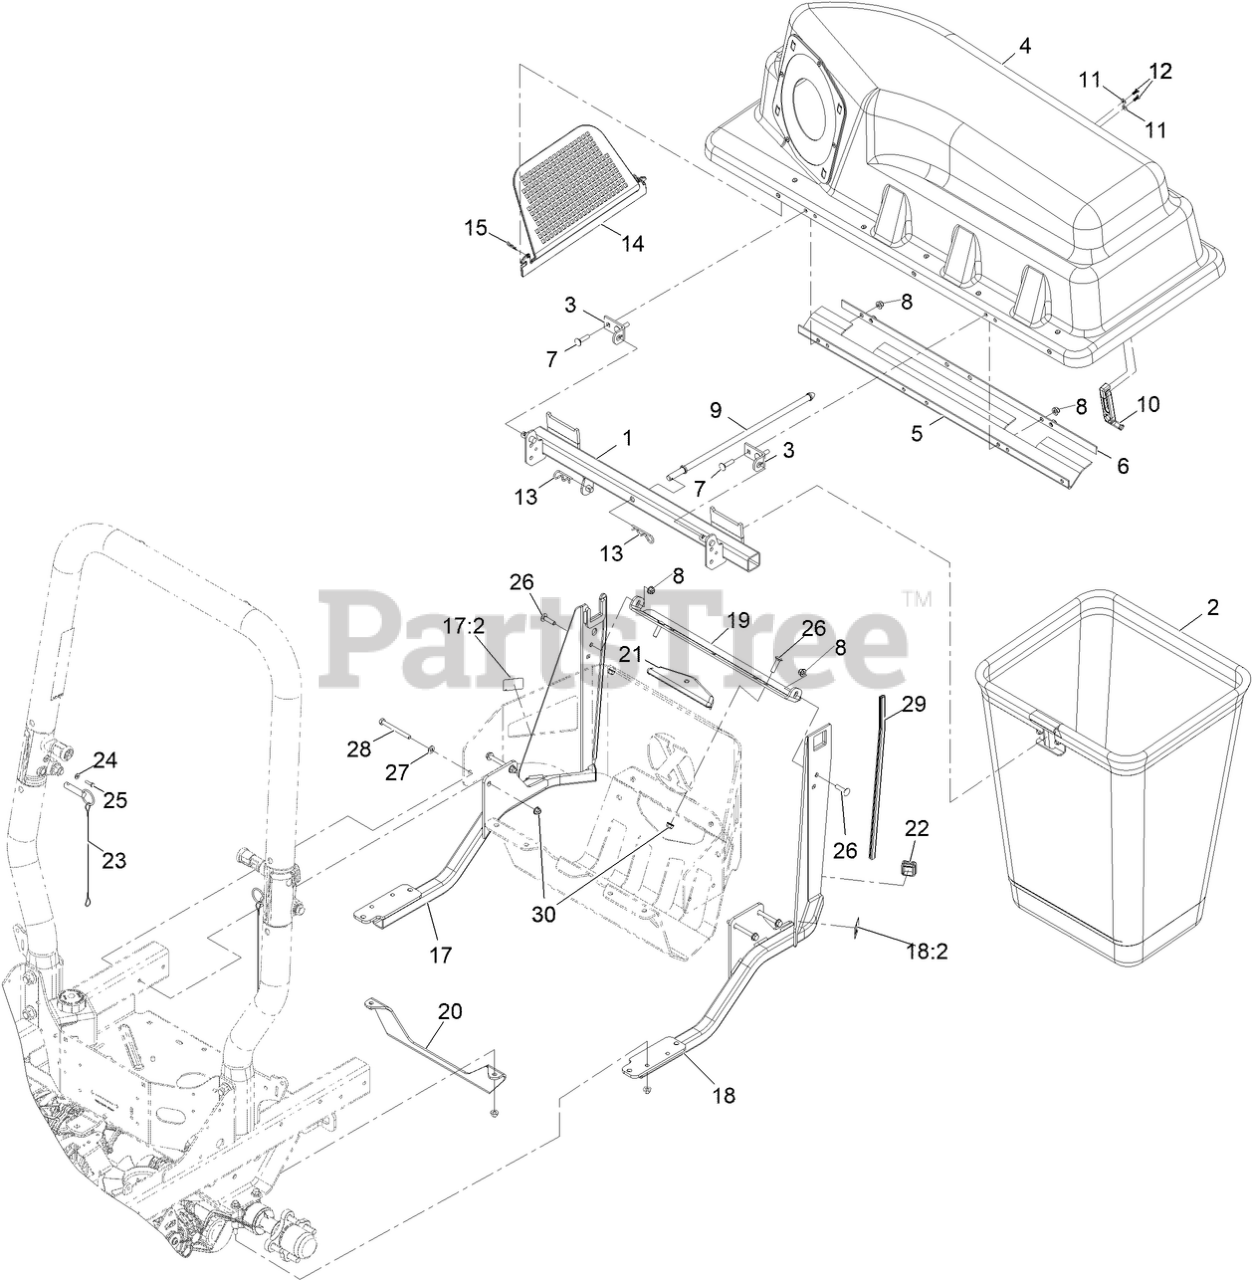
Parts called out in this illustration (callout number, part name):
1	FRAME PIVOT ASM
2	BAG AND FRAME ASM
3	BRACKET-PIVOT, HOPPER
4	BAGGER HOOD ASM
6	PLATE-BACKING
7	Bolt-Carriage 5/16-18 X 1 1/4
8	NUT-HF, NI
9	ROD-HOLD DOWN, HOOD
10	LATCH-RUBBER
11	WASHER-FLAT
12	SCREW-PLASTITE
13	PIN-HAIR
14	SCREEN-BAGGER
17	RH BAGGER SUPPORT ASM
17:2	DECAL-WARNING
18	LH BAGGER SUPPORT ASM
18:2	DECAL-WARNING
19	Angle - Support, Bagger
20	SUPPORT-TRANSMISSION
21	COVER-HITCH
23	HITCH PIN ASM
24	WASHER-FLAT
26	SCREW-CARR
27	WASHER-PLAIN
28	SCREW-HH
29	Strip-Trim
30	NUT-HF, NI
